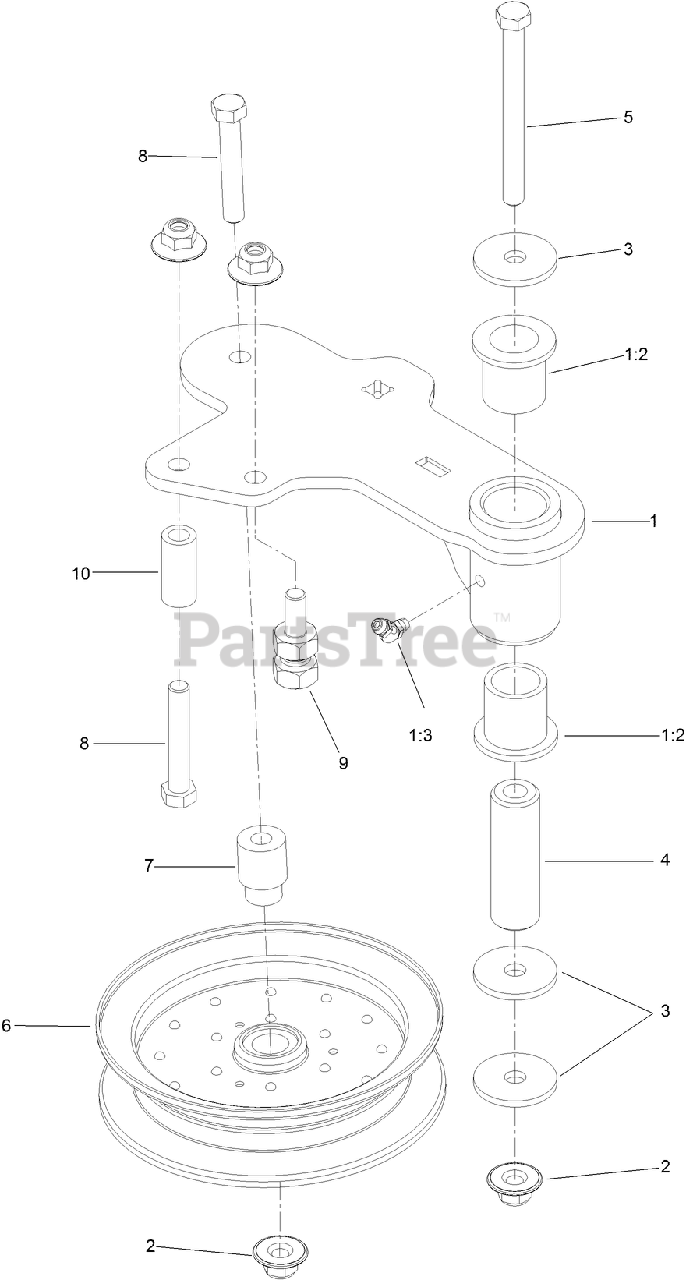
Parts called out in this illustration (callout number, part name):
1	IDLER ARM ASM
1:2	BEARING-FLANGED
1:3	FITTING-GREASE
2	NUT-FLANGE, NI
3	WASHER
4	SPACER-PLAIN
5	SCREW-HH
6	IDLER-PULLEY, FLANGED
7	MOUNT-PULLEY
8	SCREW-HH
9	ANCHOR-SPRING, SHORT
10	SPACER
